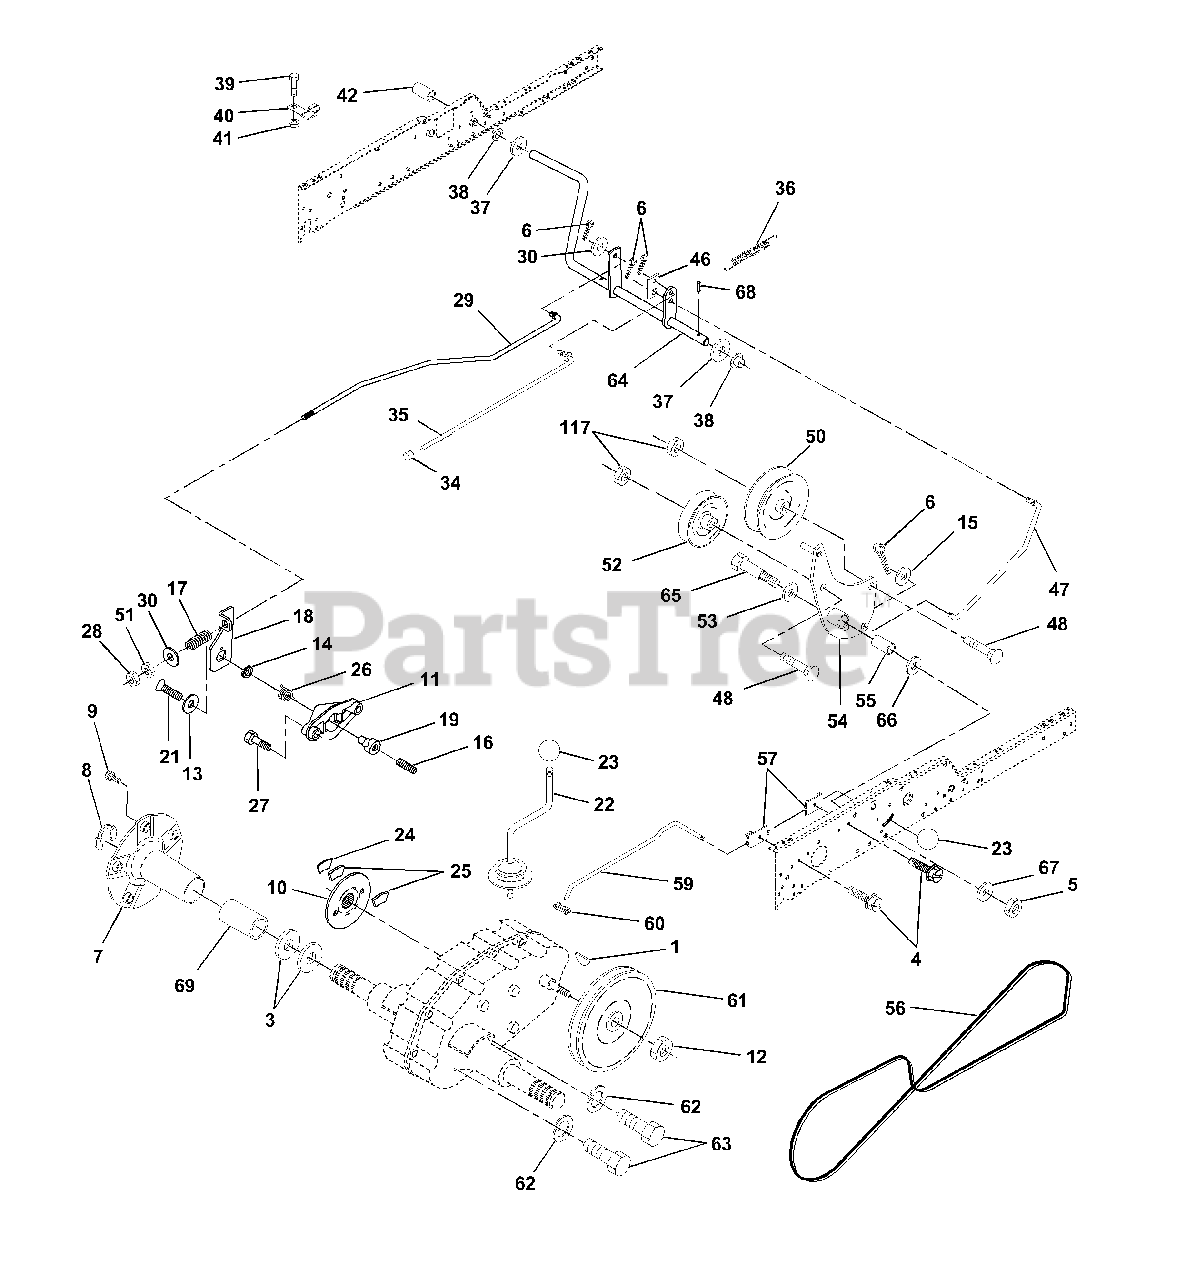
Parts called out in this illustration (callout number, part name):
1	Key, Woodruff
3	Washer, Thrust, Axle
4	Screw Thdrol 5/16-18 x 3/4
5	Nut, Crownlock 3/8-16
6	Pin, Cotter
7	Wheel, Hub Assembly
8	Klip, Ring
9	Bolt, Hub
10	Disc, Brake
11	Yoke, Brake Disc
12	Nutlock 1/2-20 Unf
13	Washer, Special
14	Bushing
15	Washer 13/32 x 13/16 x 16 Ga.
16	Set, Screw 1/4-28 x 3/4
17	Spring
18	Lever, Brake
19	Cam, Brake Disc
21	Screw, Flat Head 1/4-28 x 3/4
22	Gearshift, Lever Assembly
23	Knob
24	Support, Puck Brake
25	Puck, Brake Top
26	Spring, Return
27	Screw, Hex Wsh Thd. 5/16-18 x 1-3/4
28	Nut, Hex Jam 3/8-16
29	Brake, Rod
30	Washer 13/32 x 1 x 16 Ga.
34	Cap, Plunger
35	Rod, Parking Brake
36	Spring, Drive Ground
37	Washer 25/32 x 1-1/4 x 16 Ga.
38	Nyliner
39	Screw, Fin. #10-24 x 1
40	Actuator, Interlock Switch
41	Nut Centerlock 10-24-Umc
42	Cover, Pedal
46	Retainer, Spring
47	Clutch Rod
48	Bolt, Carriage 3/8-16 x 1-1/2 Gr. 5
50	Pulley, Idler, Flat
51	Nut, Crownlock 3/8-16 UNC
52	Pulley, Idler, Grooved
53	Washer,Hardened
54	Clutch, Arm Assembly
55	Bearing, Idler
56	V-Belt
57	Bracket, Shift Rod, Hi-Lo
59	Shift Rod, Hi-Lo
60	Spring Clip, Connecting Link
61	Pulley, Transaxle
62	Washer, Lock 7/16
63	Bolt, Fin Hex 7/16-14 x 1-1/4
64	Shaft, Clutch/Brake Pedal
65	Bolt, Shoulder
66	Washer,Hardened
67	Washer, Flat
68	Pin, Roll
69	Hub, Cover
117	Nut, Lock Flg. 3/8-16 Unc
